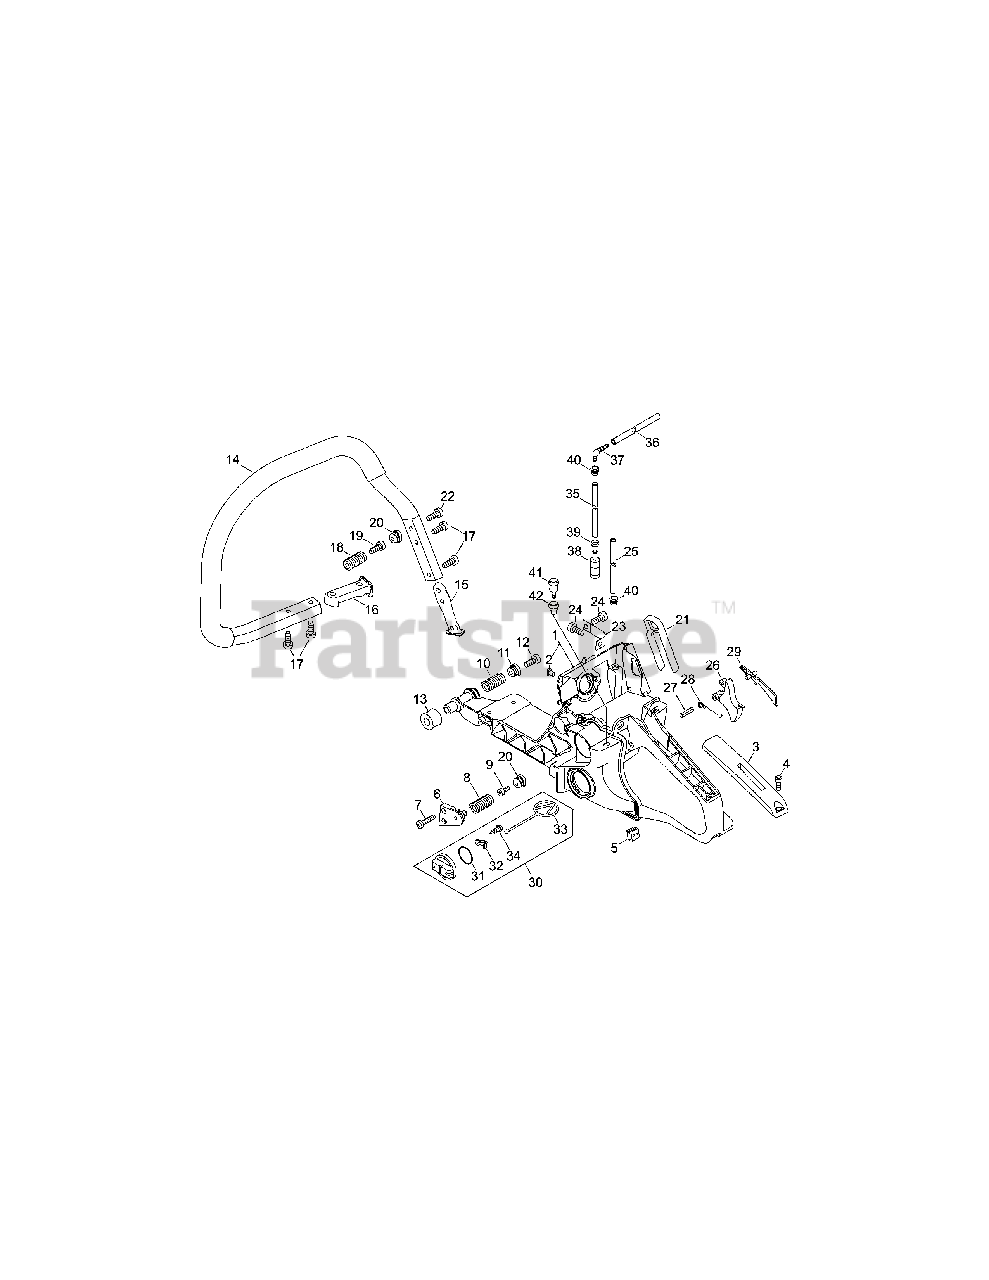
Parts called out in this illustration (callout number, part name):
1	HANDLE, REAR
3	LID,HANDLE
4	BOLT, TORX 4
6	HOLDER,SPRING
7	BOLT, TORX 5
8	SPRING,COMPRESSION
9	BOLT, TORX 5
10	SPRING,COMPRESSION
11	HOLDER,SPRING
12	BOLT, TORX 6
13	CUSHION
14	HANDLE, FRONT
15	BRACKET,HANDLE
16	BRACKET,HANDLE
17	BOLT, TORX 5
18	SPRING,COMPRESSION
19	BOLT, TORX 5
20	HOLDER,SPRING
21	HOLDER,SPRING
22	BOLT, TORX 6
23	STOPPER
24	BOLT, TORX 5
25	PIPE, IMPULSE
26	CONTROL, THROTTLE
27	PIN, SPRING 4*25SUS
28	SPRING,TORSION
29	LOCKOUT, T. CONTROL
30	CAP,FUER ASSY
31	O-RING 29
32	RETAINER, LINK
33	LINK
34	SCREW 3×8
35	PIPE
36	PIPE, IMPULSE
37	JOINT,PIPE
38	STRAINER, FUEL
40	GROMMET
41	VENT ASSEMBLY, FUEL
42	COVER,VENT
